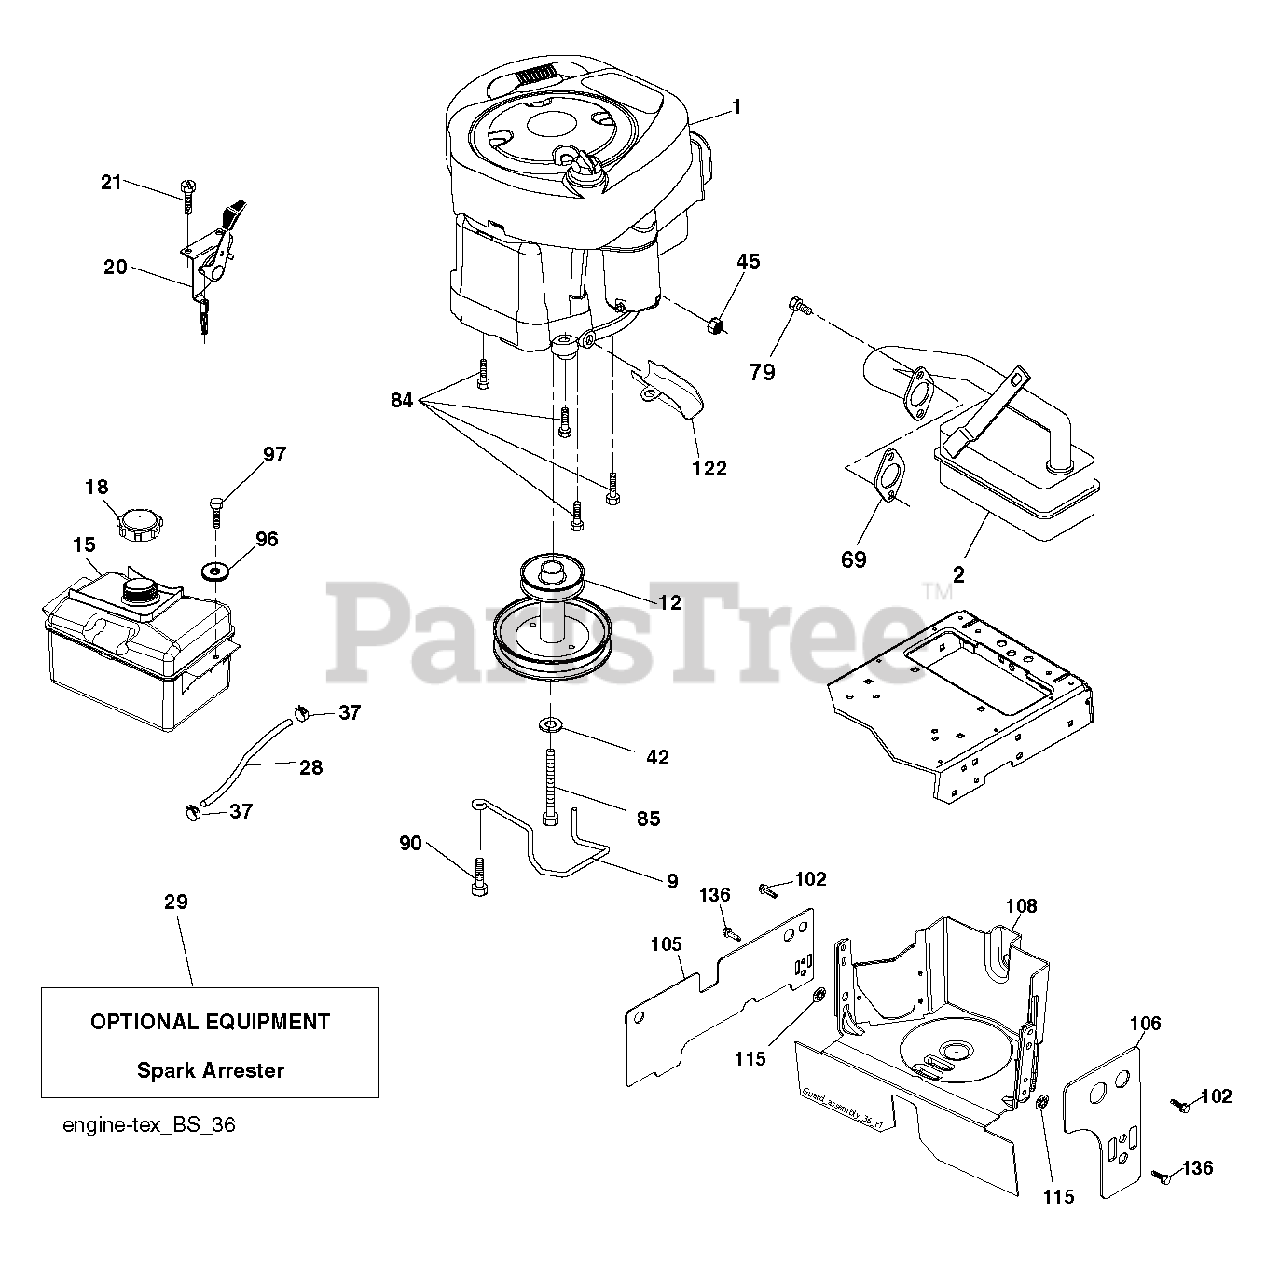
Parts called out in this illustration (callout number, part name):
9	KEEPER.BELT.ENGINE.3.25
12	PULLEY ENGINE
15	TANK FUEL FRT 1.5 GAL
18	CAP ASM.FUEL.2.25"FR.
20	CONTROL.TH/CK.C.
21	SCREW.#10 X 0.750.BOS THREAD
28	LINE.FUEL.20
29	ARRESTER SPARK (OPTIONAL)
37	HOSE CLAMP
42	LOCKWASHER
45	NUT
69	REPL BY 532 27 22-93
79	SCREW.SOCKET HD.5/16-1
84	SCREW.3/8-16
85	BOLT HEX 7/16-20X4-1/4"
90	SCREW 3/8-16X1
96	WASHER
97	SCREW HEXWSHR 1/4-20X3/4
102	SCREW
115	PALNUT 1/4
122	EXTENSION DRAIN OIL
136	SCREW.1/4-20X5/8
